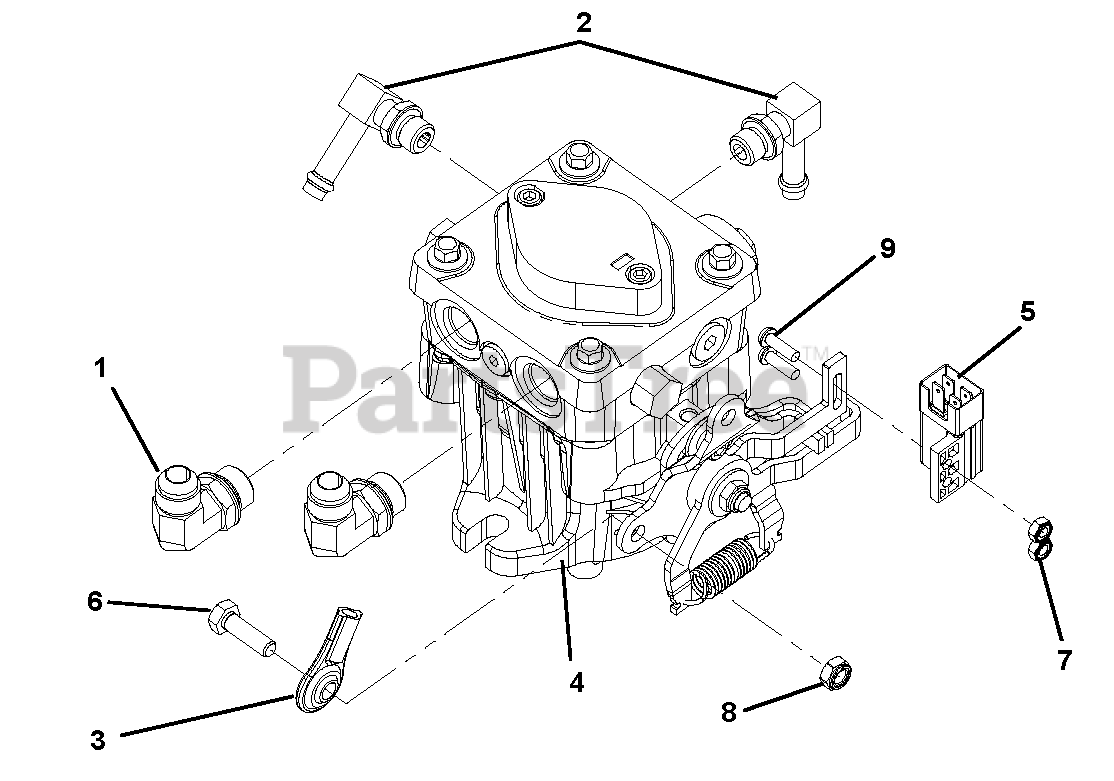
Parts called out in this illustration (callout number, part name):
1	Fitting, Includes O-Ring
2	Fitting, Adaptor .562-18 Steel Thread
3	Rod End, 5/16 RH
4	Pump, Hydraulic LH
5	Switch, Plunger Diametral Pitch -N.O. -N.C.
6	Bolt, Hex .31 x 1.00 Grade 5
7	Nut, Locking, Nylon 10-24 w/Insert
8	Nut, Locking, Nylon .312-18
9	Screw, Machine 10-24 x .62 P/HD
